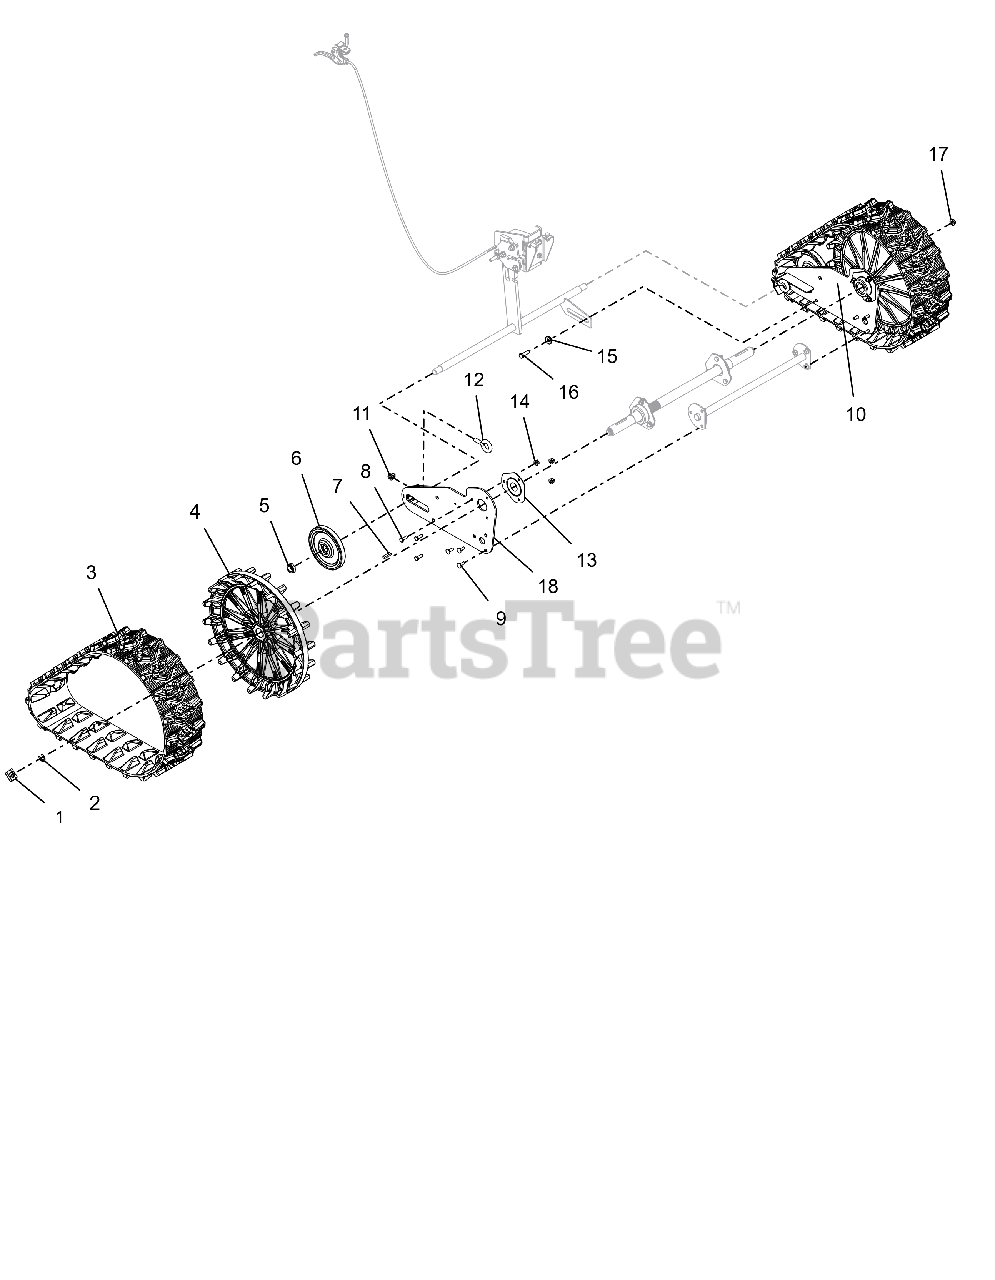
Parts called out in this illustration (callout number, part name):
1	CLIP, SNAP .625 DIA
2	RG-RTNG-EXT .625X.042
3	TRACK, RUBBER - 22 PITCHES
4	SPROCKET, LARGE TRACK DRIVE
5	@NUT-LK-NYL .625-18 YWZC
6	WHEEL, BOGIE - SINGLE BEARING
7	KEY-RECT .25X.188X1.00
8	@BLT-HEX .25-20X.75 GR5 YWZC
9	@BLT-RDHDSQNK .25-20X.75 G5YZ
10	PLATE, SIDE-BWT LH WLDMT
11	NUT-LK-CTR-FLG .38-16 YWZC
12	BLT-EYE .375-16X.880 YWZC
13	BRG-FLG 1.003/1.000 3 BOLT
14	@NUT-LK-TOP-FLG .25-20 YWZC
15	BSHG-FLG .325X.499X.3X.875
16	@BLT-HEX .31-18X1.00 GR5 YWZC
17	@NUT-LK-TOP-FLG .31-18 YWZC
18	PLATE, SIDE-BWT RH WLDMT
